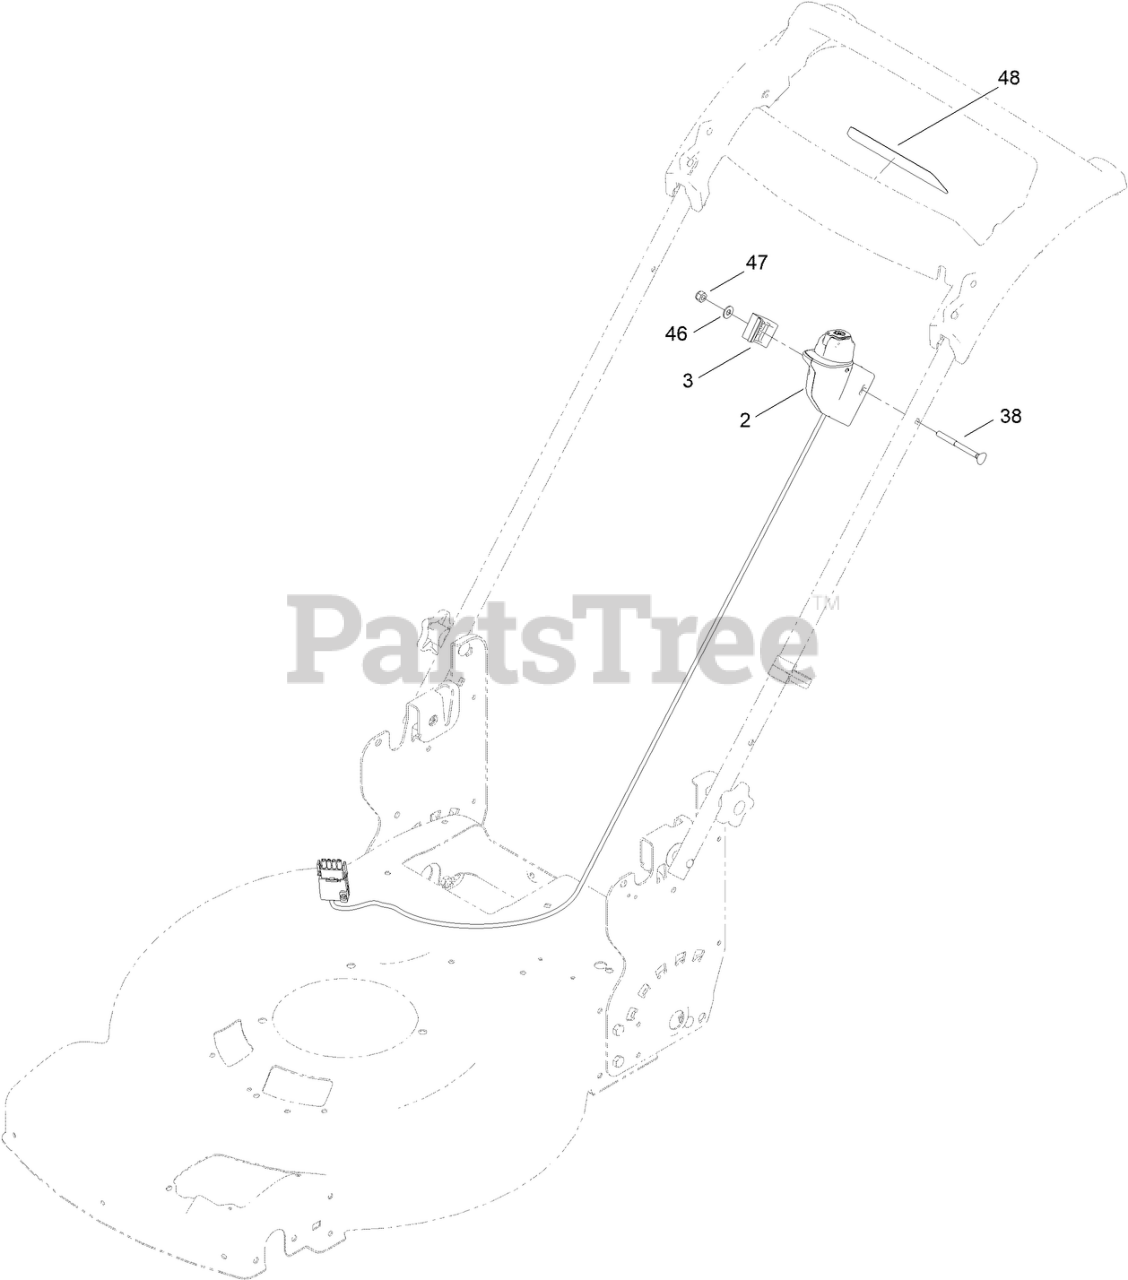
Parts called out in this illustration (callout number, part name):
2	SWITCH-STARTER ASM
3	CLAMP-CABLE
38	SCREW-HANDLE
46	WASHER-FLAT
47	NUT-LOCK, NI
48	DECAL-CONTROLS (60V, START)
